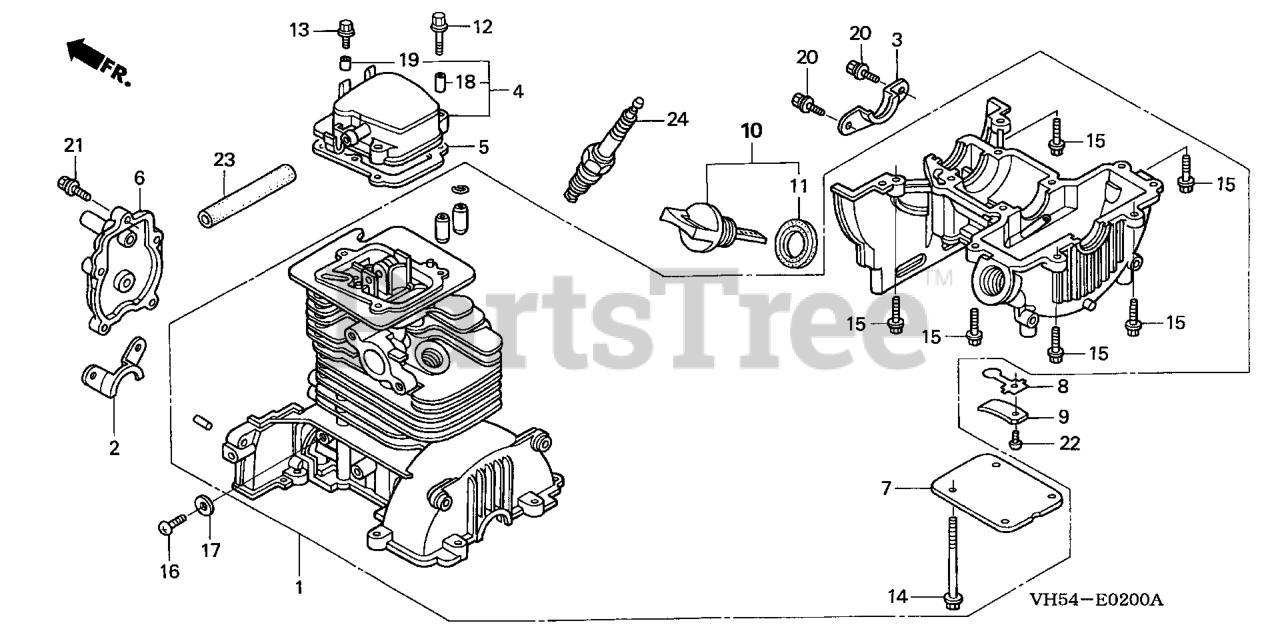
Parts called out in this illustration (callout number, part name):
1	CRANKCASE SET
2	GUARD A, GRASS
3	GUARD B, GRASS
4	COVER, HEAD
5	GASKET, HEAD COVER
6	COVER, CAMSHAFT
7	COVER, OIL OUTLET VALVE
8	VALVE, OIL OUTLET
9	PLATE, STOPPER
10	CAP ASSY., OIL FILLER
11	GASKET, OIL FILLER CAP
12	BOLT, FLANGE (5X22)
13	BOLT, FLANGE (5X14)
14	BOLT, FLANGE (5X55)
15	BOLT, FLANGE (5X18)
16	SCREW, PAN (6X8)
17	WASHER, SEALING (6.5MM)
18	COLLAR, HEAD COVER
19	COLLAR A, HEAD COVER
20	BOLT-WASHER (4X10)
21	BOLT-WASHER (4X16)
22	SCREW, PAN (3X5)
23	BULK HOSE, VACUUM (7X3000) (7X550)
24	SPARK PLUG (CR5HSB)
